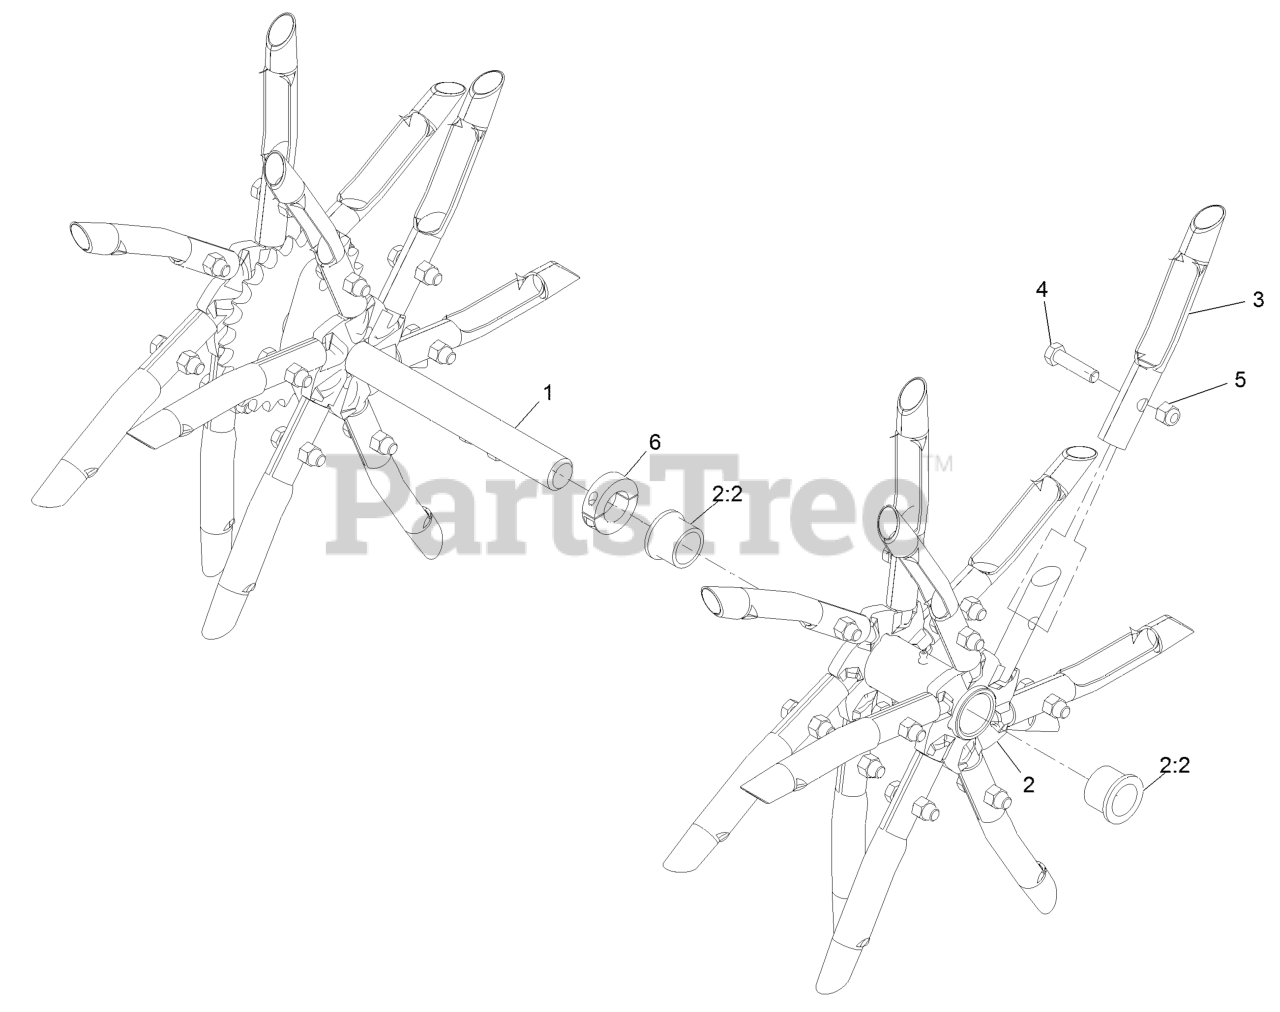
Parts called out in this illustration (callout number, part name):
2:2	BUSHING-FLANGE
4	SCREW-HH
5	NUT-LOCK, NI
6	COLLAR-LOCKING
